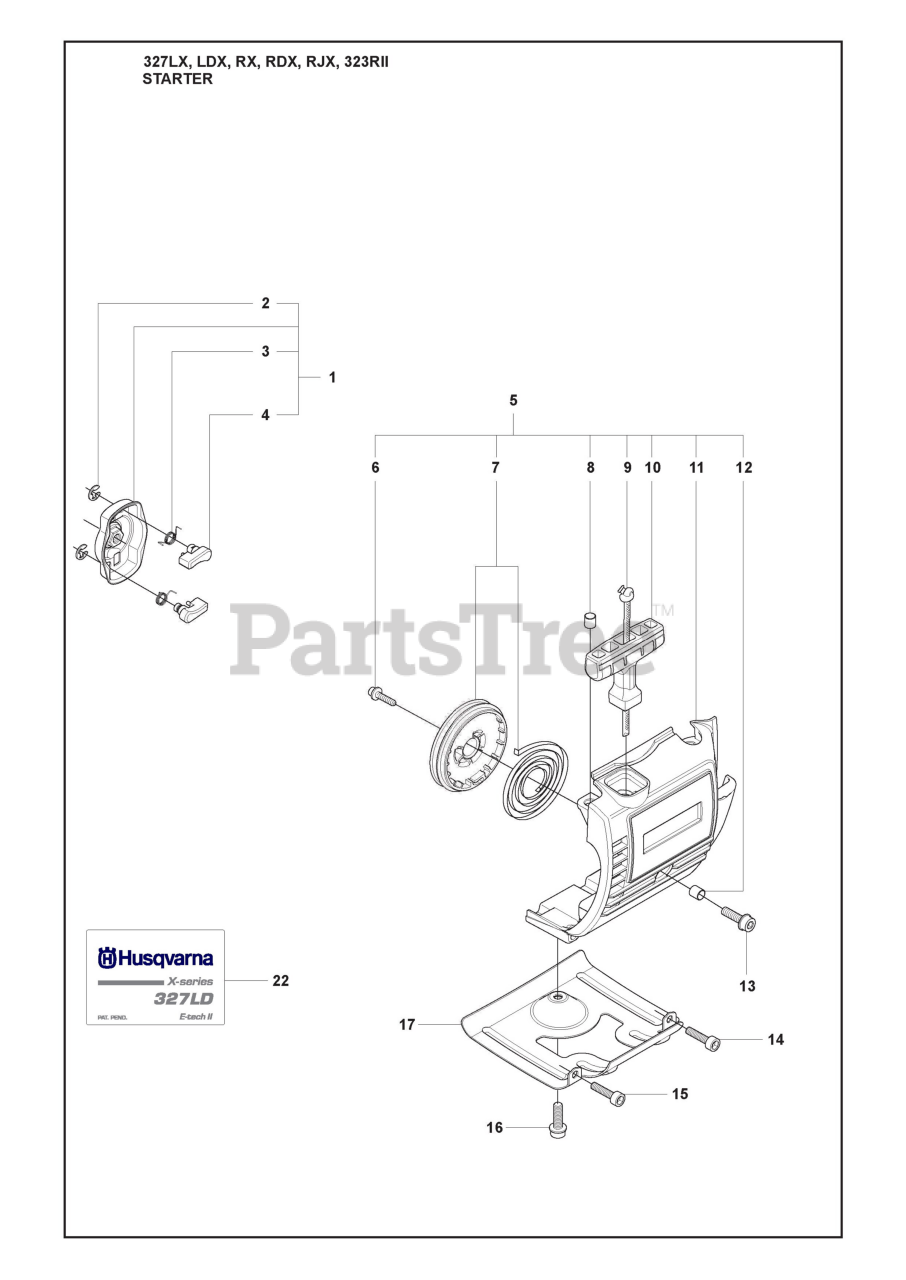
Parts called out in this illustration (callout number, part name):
1	STARTER PAWL BRIDGE
4	STARTER PAWL
5	%STARTER ASSY
7	STARTER PULLEY ASSY.
8	SPACING SLEEVE
9	STARTER ROPE
10	STARTER HANDLE
11	RP STARTER HOUSING
12	SPACING SLEEVE
13	SCREW
16	SCREW
